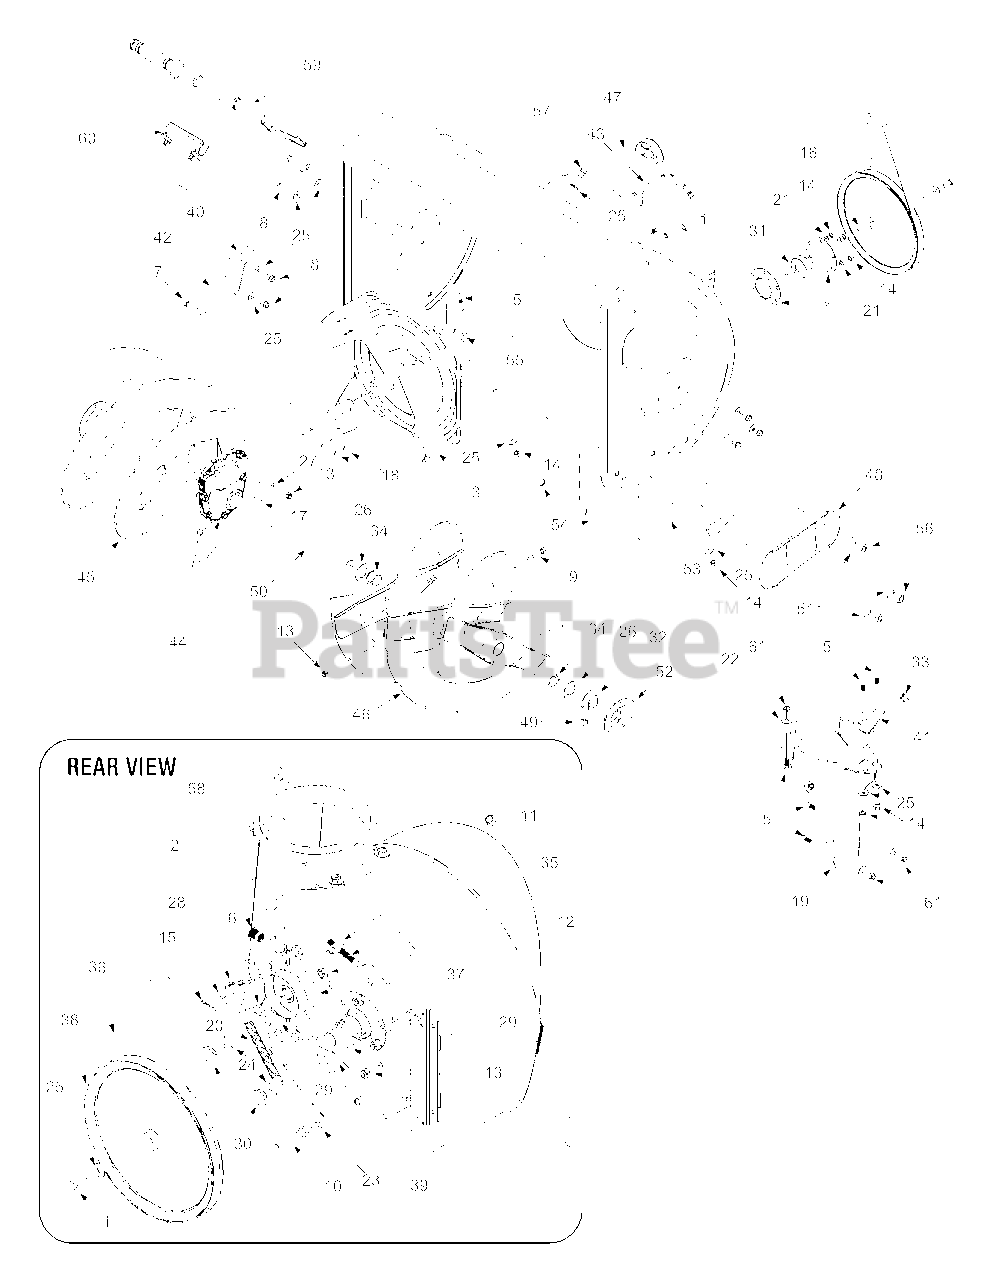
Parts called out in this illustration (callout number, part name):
1	Bearing Housing
2	Bracket Assembly: Auger Break
5	Carriage Bolt 5/16-18 x .750"
6	Hex Screw, Special 3/8-24 x 1.5"
7	Hex Screw 5/16-18 x 1.25"
8	Self-Tapp. Screw 5/16-12 x .75"
9	Shear Bolt 5/16-18 x 1.75"
11	Ferrule
12	Jam Nut 3/8-24
13	Hex Lock Nut 5/16-18
14	Hex Nut 5/16-18
15	Hairpin Clip
18	Spiral Pin
19	Chute Adapter
20	Extension Spring
21	Lock Washer
22	5/16 Washer
23	Lock Washer
24	Wave Washer
25	Beleville Washer
26	Flat Washer
27	Spring Washer
28	Flat Washer
30	Shoulder Screw
31	Self-Aligning Bearing
32	Flange Bearing w/ Flats
33	Plastic Bushing
34	Flange Bushing
35	Idler Rod: Auger
36	V-Belt
37	Flat Idler
49	Lube Fitting
50	Axle, Auger
51	Bell Washer
54	Carriage Screw
55	Carriage Bolt
56	Hex Nut 3/8-16
57	Screw, 5/16-18 x .75
58	Insert Nut, 3/8-16
59	Chute Clean-out Tool
60	Mount, Chute Clean-out Tool
61	Nut, Flangelock 5/16-18
